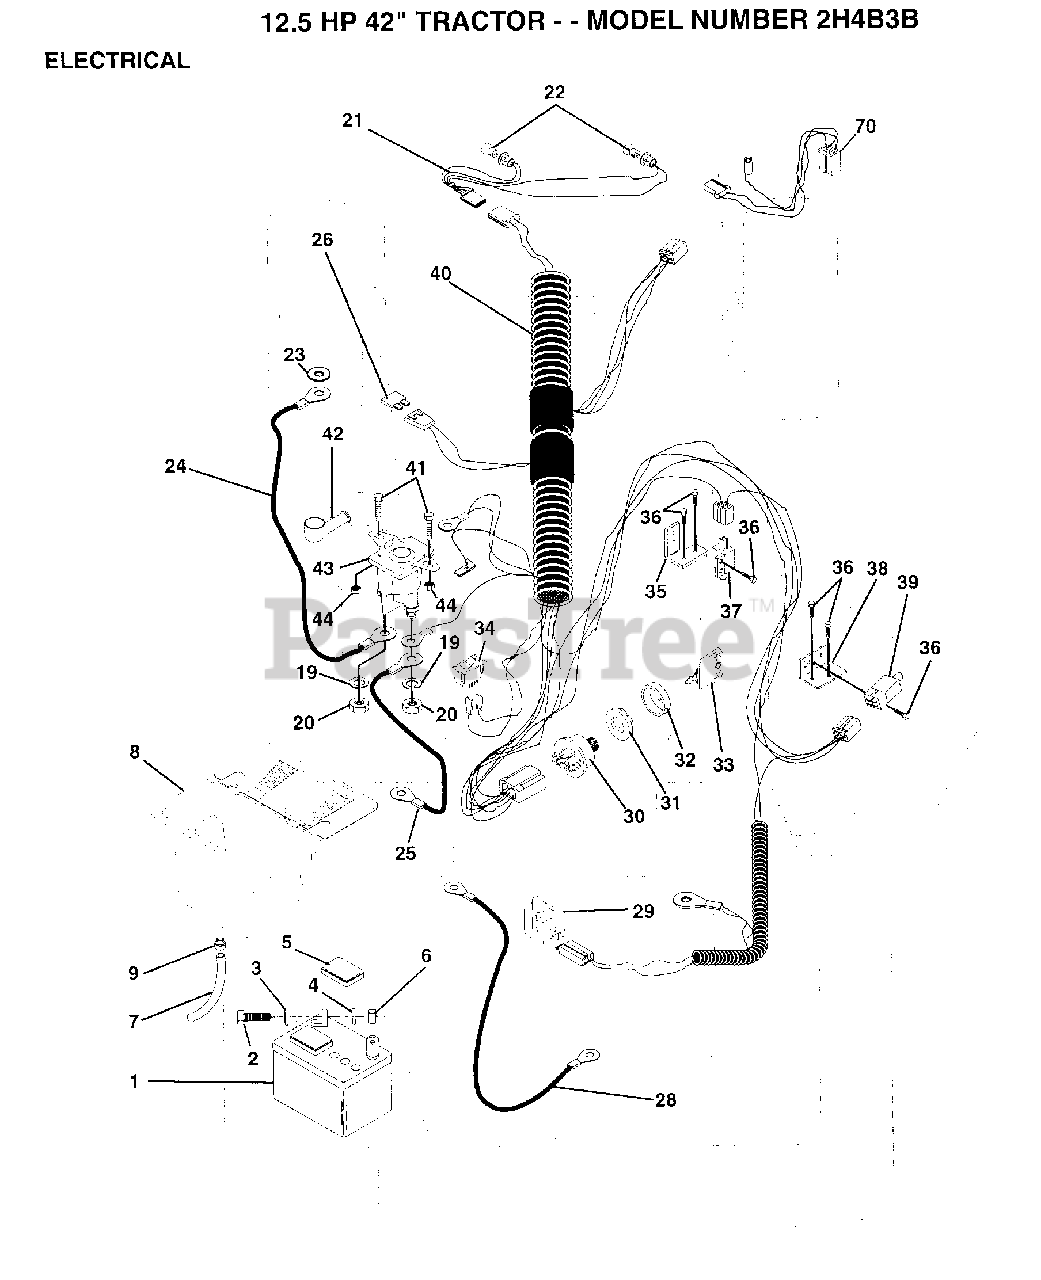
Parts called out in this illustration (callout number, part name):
2	BOLT LT
3	WASHER
4	LOCKWASHER
5	"CAP,BATTERY "
7	TUBE T
9	HOSE CLAMP T
20	NUT
21	"HARNESS,LIGHT SOC"
22	HEADLAMP BULB
23	LOCKWASHER
24	"CABLE T, BATTERY"
26	FUSE HYT
28	CABLE T
29	SWITCH SEAT
32	COVER KEY SWITCH
33	KEY MLD GEN DELTA
34	SWITCH LT
35	BRACKET LT
36	SCREW
37	SWITCH-INTER. GT
38	BRACKET SWITCH IN
39	SWITCH INTERLOCKT
40	HARNESS IGN DASH
41	BOLT HXHD FIN
44	NUT HXKEP 1/4X20
70	HARNESS ENG DUAL
